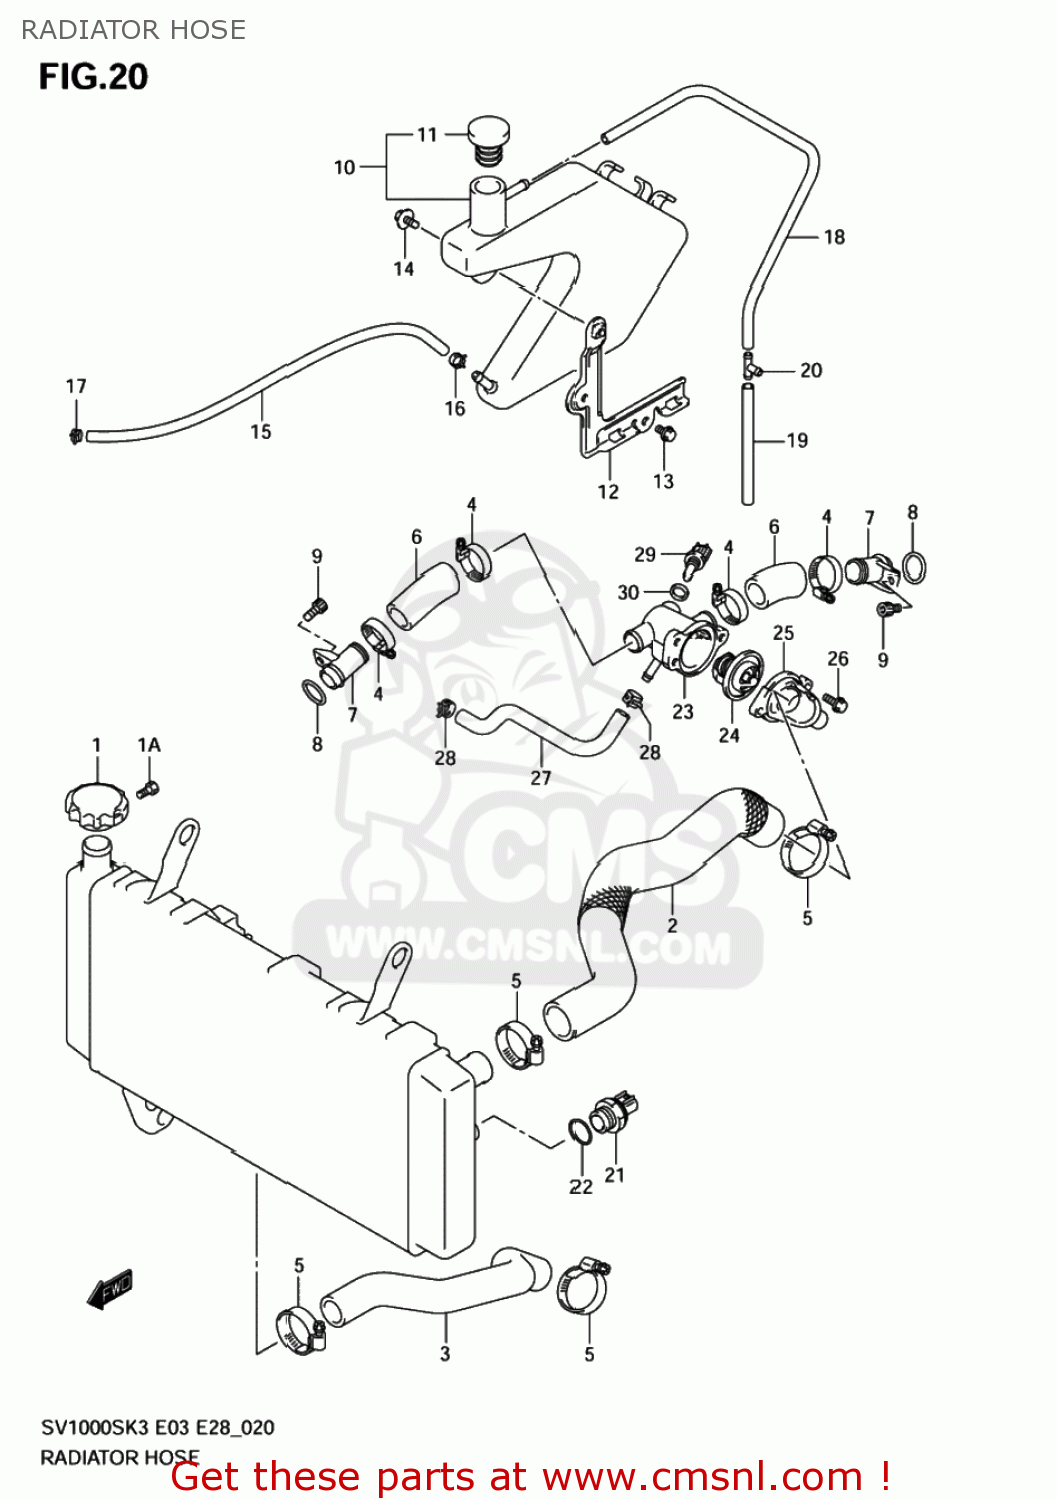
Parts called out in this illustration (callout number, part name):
1	CAP,RADIATOR
1A	SCREW,RADIATOR CAP
2	HOSE,RADIATOR INLET
3	HOSE,RADIATOR OUTLET
4	CLAMP
5	CLAMP
6	HOSE,CONNECTOR INLET
7	UNION,CONN HOS
8	O RING(D:3.2,ID:17.8)
9	BOLT,STRANGER
10	TANK ASSY,RESERVOIR
11	CAP,RESERVOIR TANK
12	BRACKET,RESERVOIR TANK
13	BOLT
14	BOLT 6X14
15	HOSE(5X9X600)
16	CLIP
17	CLIP
18	HOSE(5X9X600)
19	HOSE(7X10.2X600)
20	3 WAY
21	SWITCH,RADIATOR FAN
22	O-RING
23	CONNECTOR,THERMOSTAT INLET
24	THERMOSTAT,WATER
25	CAP,THERMOSTAT CONNECTOR
26	BOLT
27	HOSE,WATER BYPASS
28	CLAMP
29	SENSOR,WATER TEMP
30	GASKET(12X17X1) (NAS)
